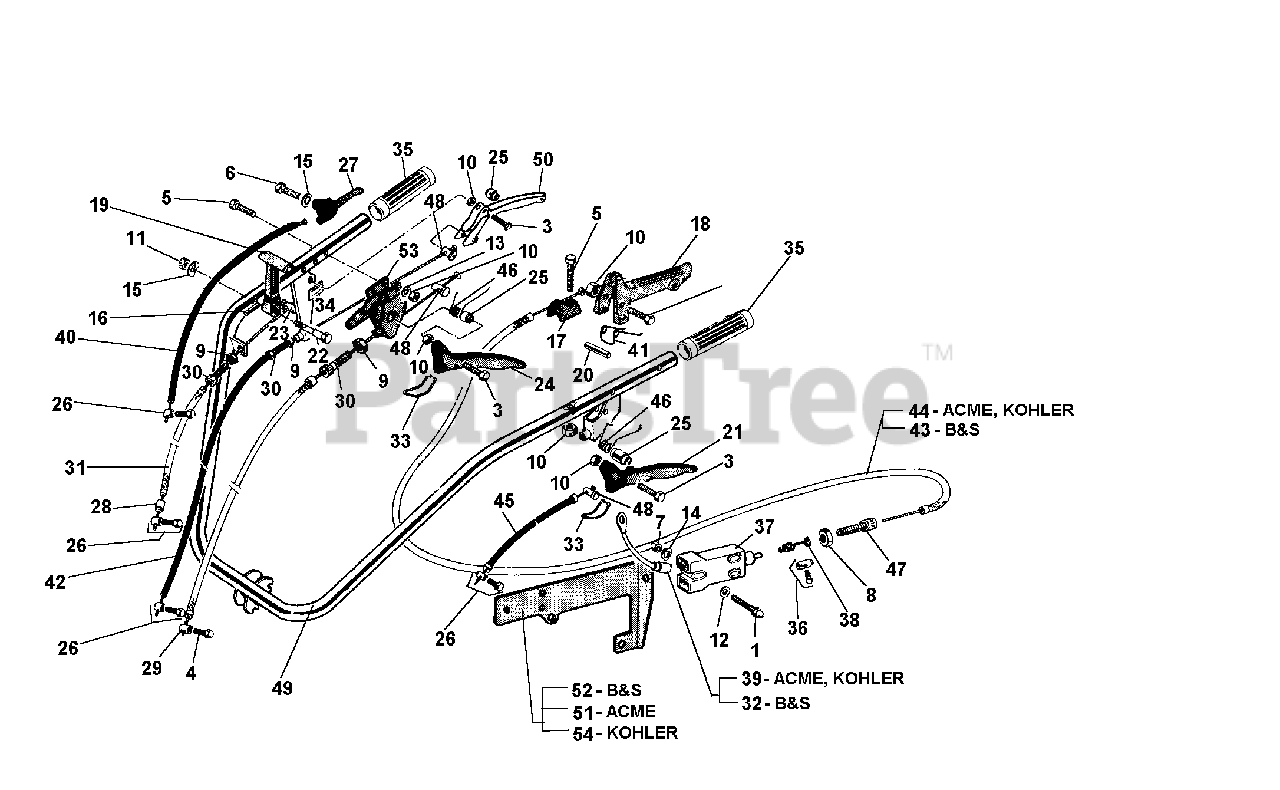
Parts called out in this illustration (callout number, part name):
1	SCREW TE M4 X 25
2	SCREW TE M6 X 45
3	SCREW M6 X 25
4	SCREW TE M6 X 16
5	SCREW M6 X 35
6	SCREW TE M8 X 40
10	NUT, SELF LOCKING M6
11	NUT, SELF LOCKING M8
12	FLAT WASHER 4.3
13	WASHER, LOCK 6.4
14	LOCK WASHER B 4.3
15	WASHER, LOCK 8.4
16	PIN, LOCKING 4 X 20
17	SHEATH STOP OF MOTOR STOP
18	MOTOR STOP LEVER
19	LEVER DIFFERENTIAL LOCKING
20	LEVER STOP FOR MOTOR STOP
21	CLUTCH LEVER
23	DRILLED PIN
25	LEVER SPACER
26	CLAMP, CABLE
27	LEVER, ACCELERATOR
29	PIN, CABLE CLAMP
30	SCREW, ADJUSTING M8
31	CABLE, CLUTCH
32	SWITCH WIRE 12.5 B&S
34	REVERSER STICKER
36	CABLE CLAMP
37	STOP SWITCH
38	SWITCH SPRING
39	SWITCH CABLES
40	CABLE, ACCELERATOR
41	MOTOR STOP LEVER SPRING
42	CABLE, REVERSER
43	CABLE, STOP 12.5 B&S
44	CABLE, STOP, ACME & KOHLER
45	CABLE, CLUTCH
46	LEVER SPRING
47	ADJUSTING SCREW
50	REVERSE SPEED LEVER
51	STOP SWITCH SUPPORT, ACME
52	STOP SWITCH SUPPORT, 12.5 B&S
53	COUPLING FOR DOUBLE LEVER
54	STOP SWITCH SUPPORT, KOHLER
